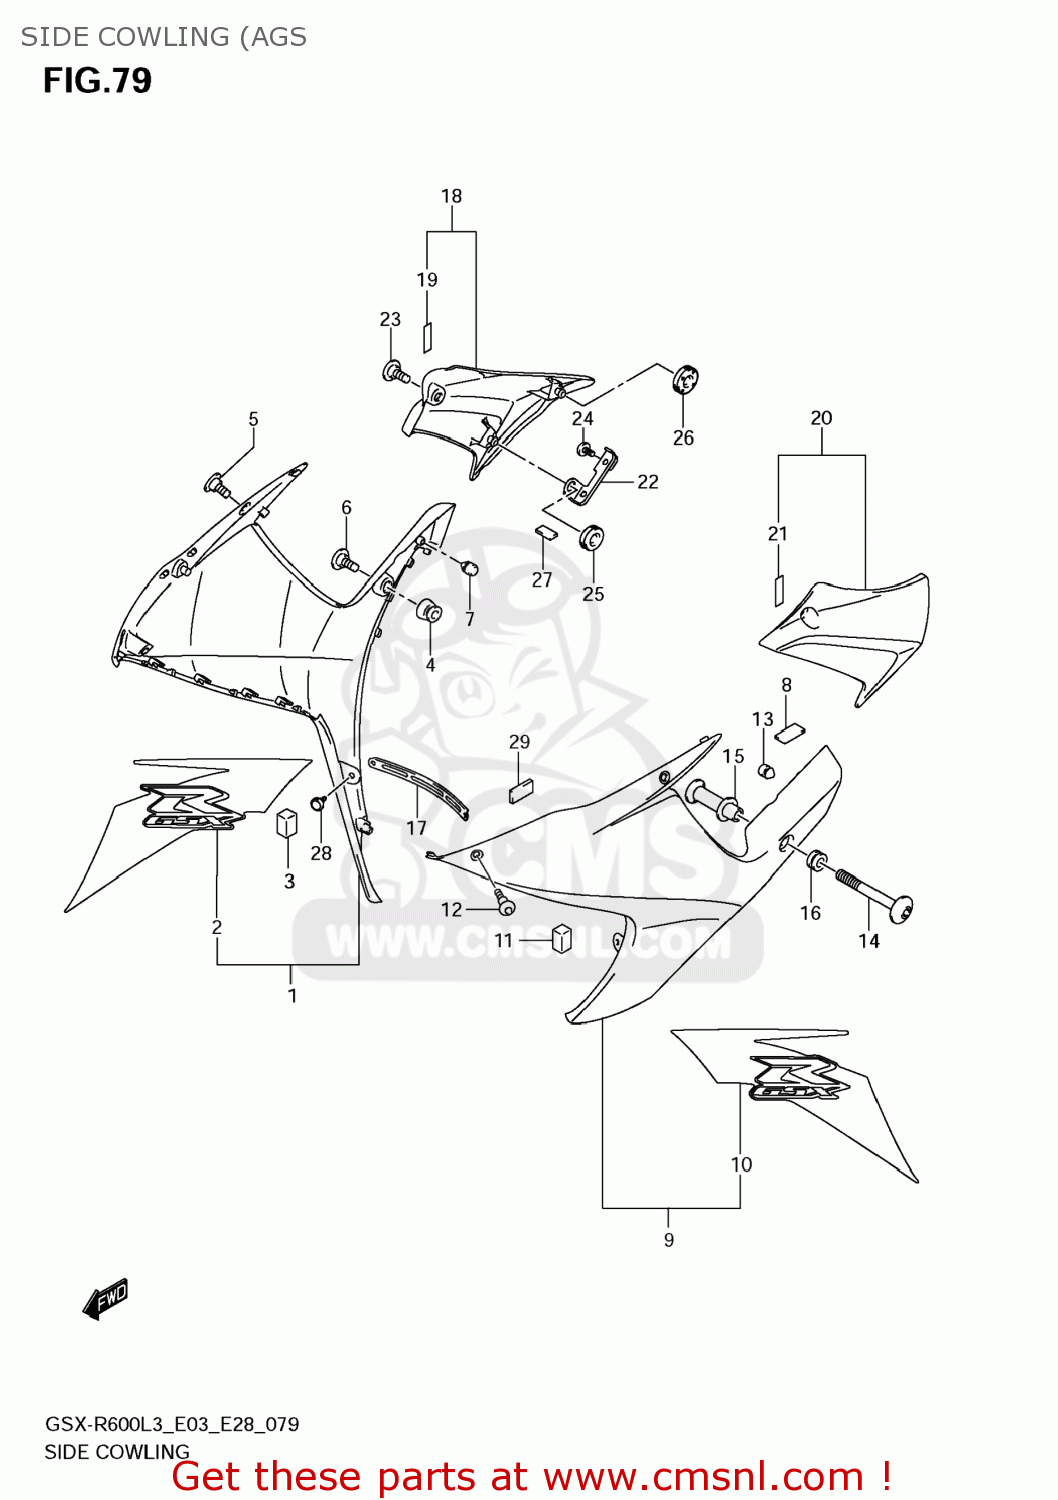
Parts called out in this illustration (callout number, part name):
1	COWLING,SIDE,R(WHITE)
2	TAPE,SIDE COWLING,R
3	CUSHION,SIDE COWL FR
4	CUSHION,UNDER COWLING,L
5	SCREW(5X13)
6	BOLT(6X20)
7	CUSHION
8	CUSHION,FUEL TANK NO.2
9	COWLING,SIDE,L(WHITE)
10	TAPE,SIDE COWLING,L
11	CUSHION,SIDE COWL FR
12	SCREW(5X13)
13	CUSHION
14	SCREW,SIDE COWL,L
15	SPACER,SIDE COWL,L
16	CUSHION
17	PLATE,UNDER COWL CTR
18	COVER,SIDE COWLING,R
19	TAPE(6X25X0.13)
20	COVER,SIDE COWLING,L
21	TAPE(6X25X0.13)
22	BRACKET,COVER SIDE,R
23	SCREW(5X13)
24	SCREW(6X12)
25	CUSHION
26	CUSHION
27	CUSHION
28	CLIP
29	PROTECTOR(30X80X1)
